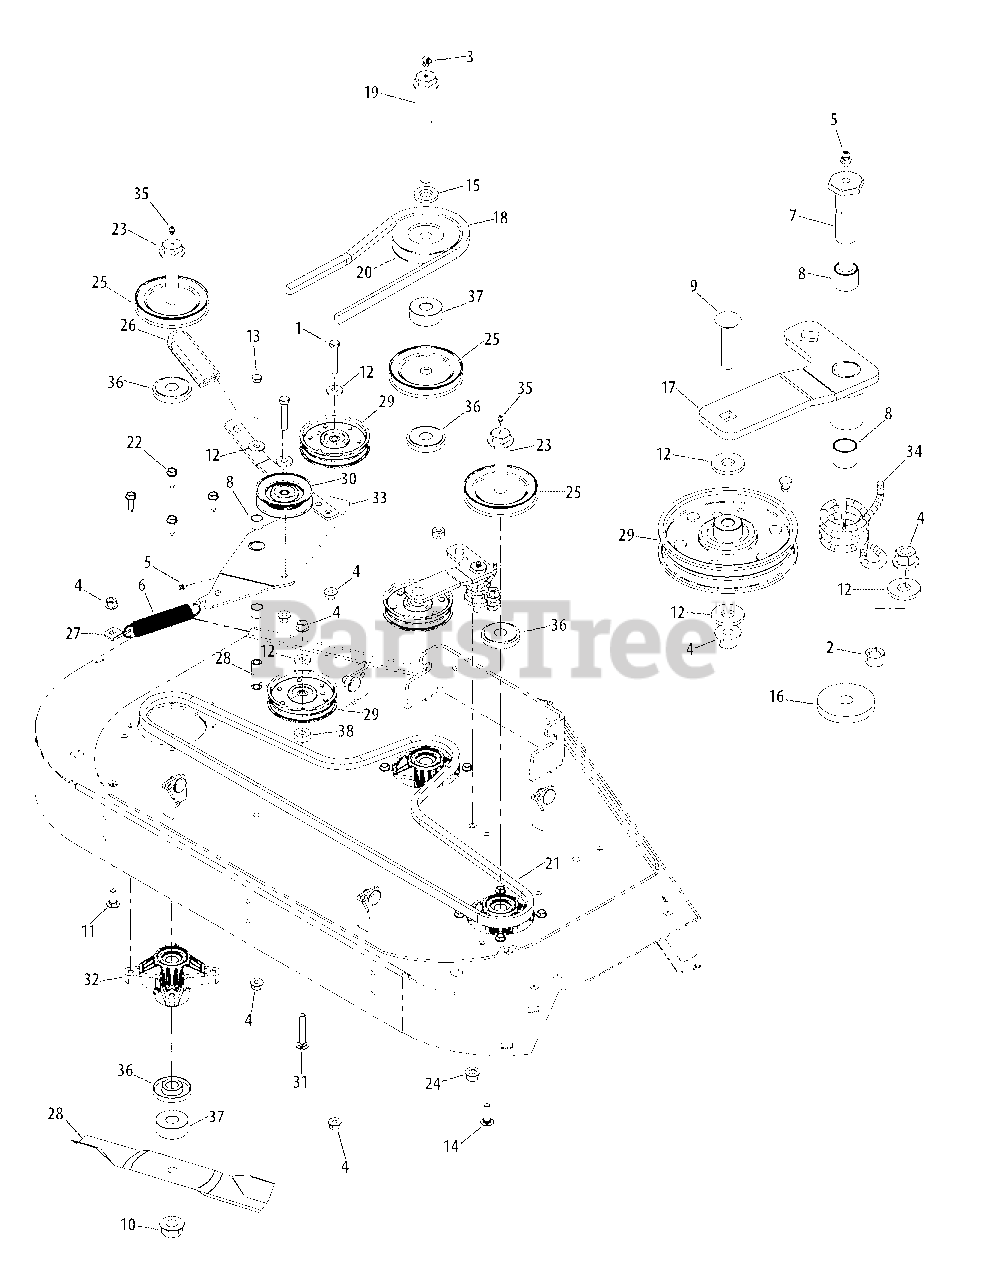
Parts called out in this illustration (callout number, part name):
1	Hex Screw, 3.8-16 x 2.00
2	Nut, 3.8-16
3	Grease Fitting, 1.4-28 x .788
4	Flange Counterlock Nut, 3/8-16
5	Grease Fitting, 1.4-28
6	Extension Spring, 1.00 x 5.00 x .125
7	Shoulder Bolt, .625 x 1.95
8	Sleeve Bearing, .628 x .753 x .625
9	Carriage Bolt, 3.8-18 x 1.75
10	Flange Nut, 3.4-16
11	Carriage Bolt, 3.8-16 x 1.00
12	Washer, .406 x 1.00 x .105
13	Hex Screw, 3.8-16 x 2.75
14	Carriage Bolt, 3.8-16 x 1.25
15	Spacer, .812 x 1.47 x .218
16	Washer, .438 x 1.75 x .250
17	Idler Arm Assembly
18	V-Belt
19	Spindle Bolt, 3.4-16 x 7.155
21	V-Belt
22	Hex Washer Screw, 5.16-18 x 1.00
23	Spindle Bolt, 3.4-16 x 5.37
24	Flange Lock Nut, 7.16-14
25	V-Type Pulley
26	Flat Grip, 1.0 x 3.2 x .25
27	Spring Mount Bracket
29	Riveted Idler Pulley
30	V-Type Idler Pulley
31	Carriage Bolt, 3.8-16 x 2.25
32	Deck Spindle Assembly
33	Weld Idler Double
34	Torsion Spring, 1.10 x 1.3
35	Drive Lube Fitting
36	Spindle Deck Spacer
37	Spacer, .760 x 2.000 x .790
38	Spacer, .406 x 1.00 x .38
